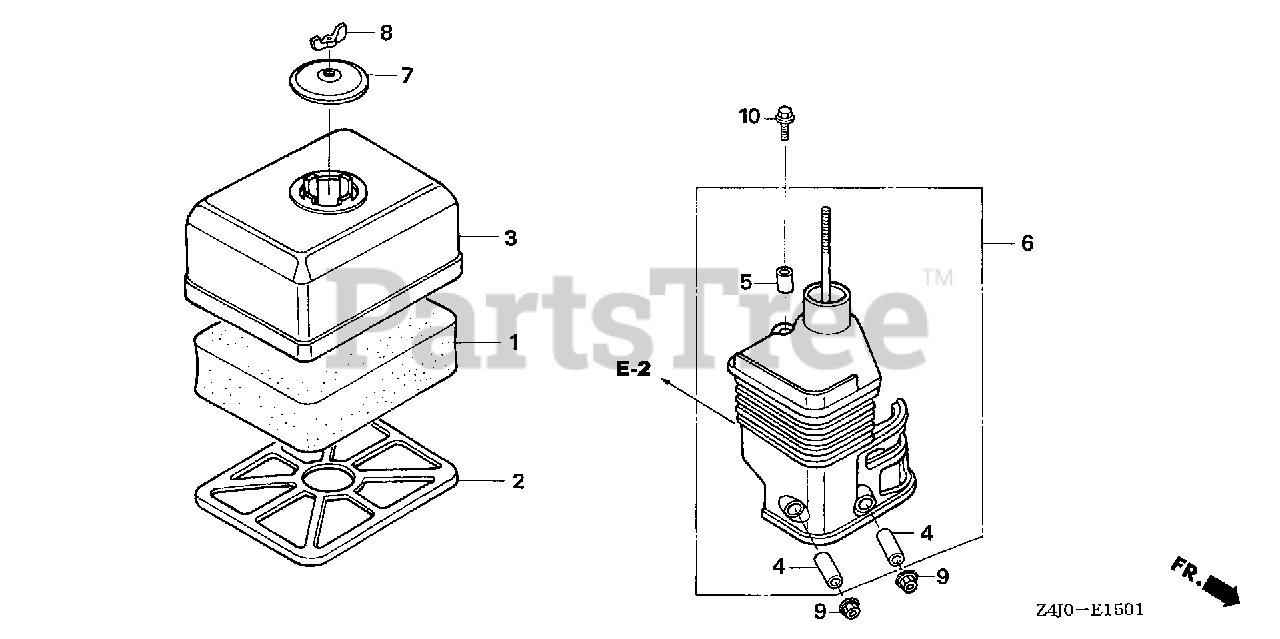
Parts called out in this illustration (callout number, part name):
1	ELEMENT, AIR CLEANER (SEMI-DRY)
2	GRID, AIR CLEANER (SEMI-DRY)
3	COVER, AIR CLEANER (SEMI-DRY)
4	COLLAR, AIR CLEANER
5	COLLAR B, AIR CLEANER
6	ELBOW, AIR CLEANER
7	CAP, CLEANER
8	NUT, TOOL BOX SETTING
9	NUT, FLANGE (6MM)
10	BOLT, FLANGE (6X20)
